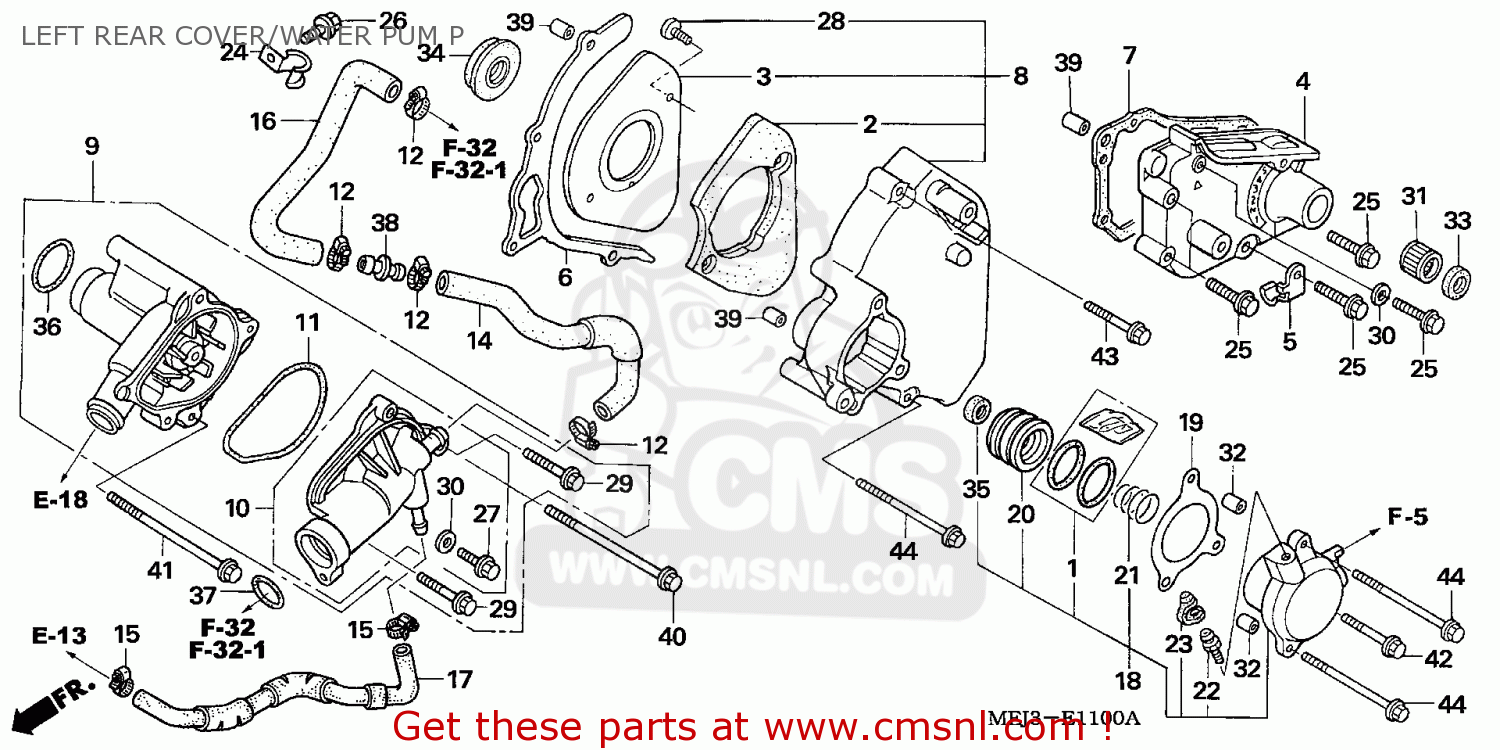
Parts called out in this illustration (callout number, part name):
1	O-RING SET
2	RUBBER,L REAR COV
3	PLATE,L REAR COVE
4	HOLDER COMP,L SID
5	CLIP,RESERVE TANK
6	PLATE,DRIVE CHAIN
7	GASKET,L SIDE HOL (NAS)
8	COVER ASSY,CRANKC
9	PUMP ASSY,WATER
10	COVER,WATER PUMP
11	GASKET,WATER PUMP
12	CLAMP,WATER HOSE,
14	HOSE SET,BYPASS A
15	CLAMP,RADIATOR HO
16	HOSE BYPASS B
17	HOSE C,WATER
18	SLAVE CYLINDER AS
19	GASKET,SLAVE CYLI (NAS)
20	PISTON,SLAVE CYLI
21	SPRING,SLAVE CYLI
22	SCREW,BLEEDER
23	CAP,BLEEDER
24	CLAMP,WATER HOSE
25	BOLT,FLANGE,NSHF,
26	BOLT,FLANGE,NSHF,
28	SCREW,PAN,6X14
29	BOLT,FLANGE,6X25
30	WASHER,SEALING,6.
31	NEEDLE,BRG
32	PIN,DOWEL,8X10
33	OIL SEAL,13X22X5
34	OIL SEAL,8X25X7
35	OIL SEAL,8X18X5
36	O-RING 32.95X2.62
37	O RING,24X3
38	JOINT,HOSE
40	BOLT,FLANGE,6X100
41	BOLT,FLANGE,6X85
42	BOLT,FLANGE,SH,6X25
43	BOLT,FLANGE,6X45
44	BOLT,FLANGE,6X75
